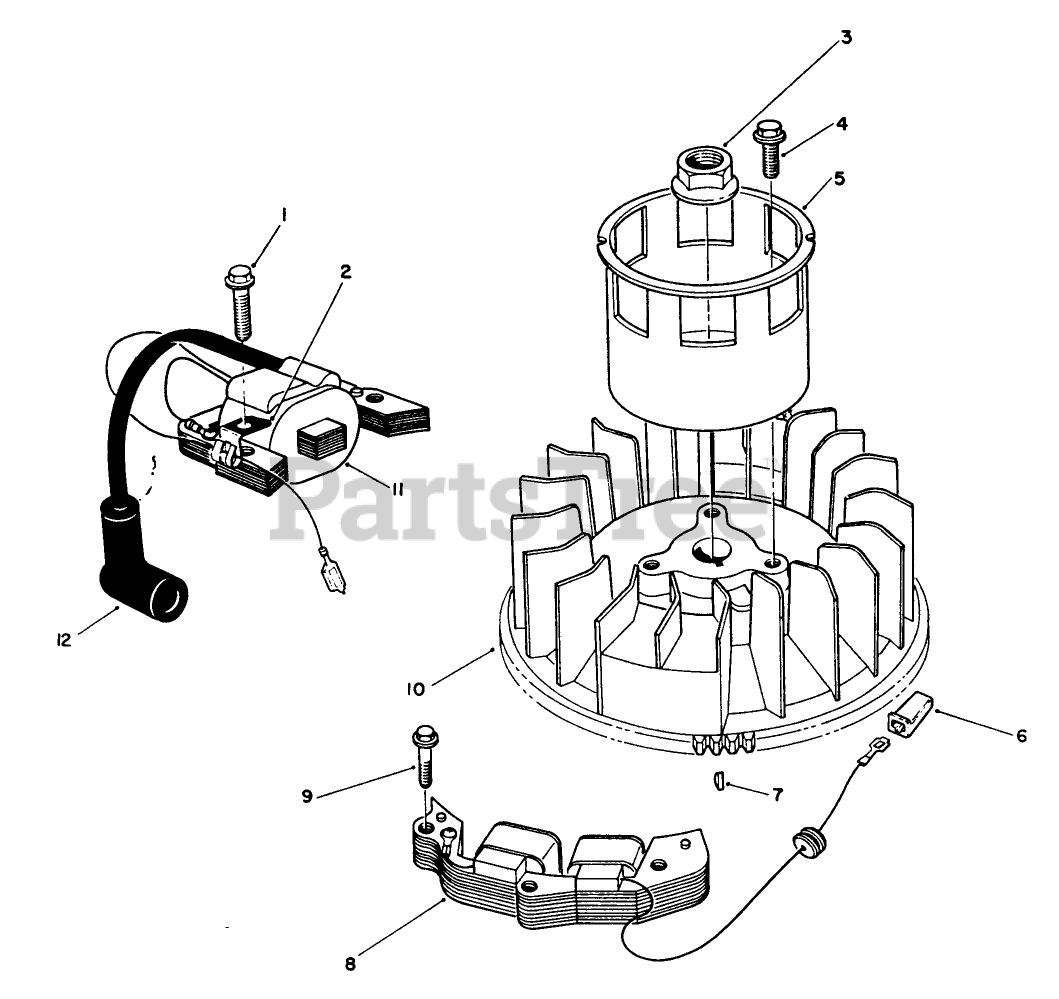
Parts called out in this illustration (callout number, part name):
2	CLAMP
6	Connector-Wire
10	FLYWHEEL
11	COIL ASM
12	COVER
